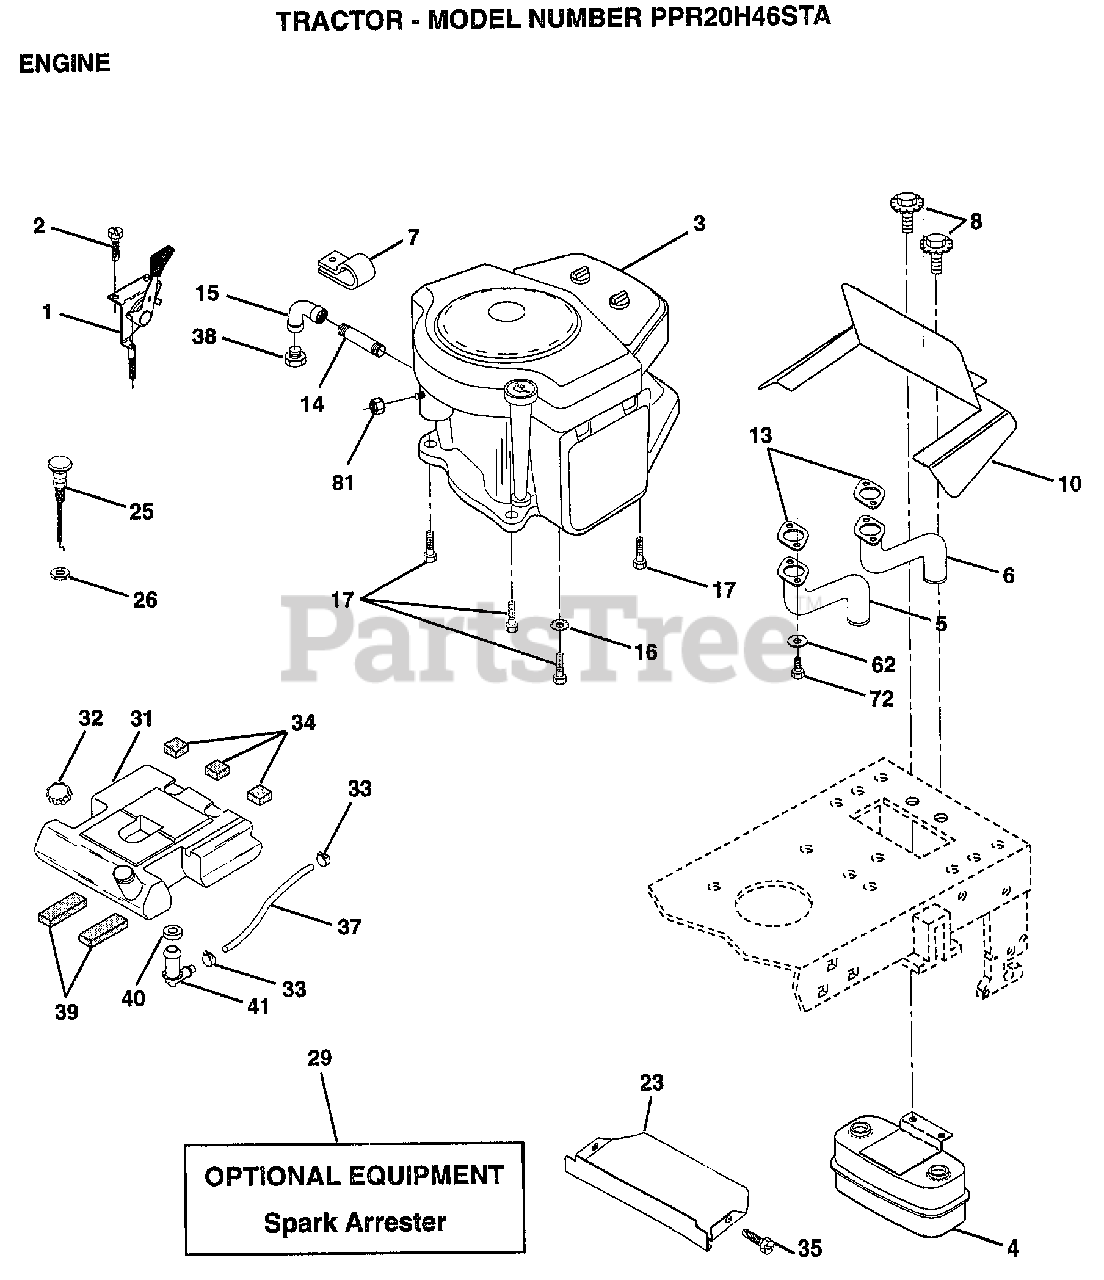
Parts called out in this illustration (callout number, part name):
1	CONTROL THROT. LH
2	SCREW LT
4	MUFFLER.TW.LOTONE
5	TUBE MANIFOLD LH
6	TUBE MANIFOLD RH
7	"CLIP,INSULATOR"
8	BOLT.5/16-18.UNC
10	SHIELD.BROWNING
14	PIPE NIPPLE LT
15	ELBOW
16	LOCKWASHER
17	SCREW LT
23	SHIELD.BRN/DBR.GD
25	CONTROL.CHOKE.37
26	"NUT,KEPS 3/8-24IM"
31	TANK FUEL REAR
32	CAP ASM FUEL
33	HOSE CLAMP
34	PAD-SPACER LT
35	SCREW
37	FUEL LINE T
39	PAD IDLER TI
40	BUSHING OUTLET T
41	STEM.TANK.FUEL
62	LOCKWASHER
72	SCREW
81	NUT
